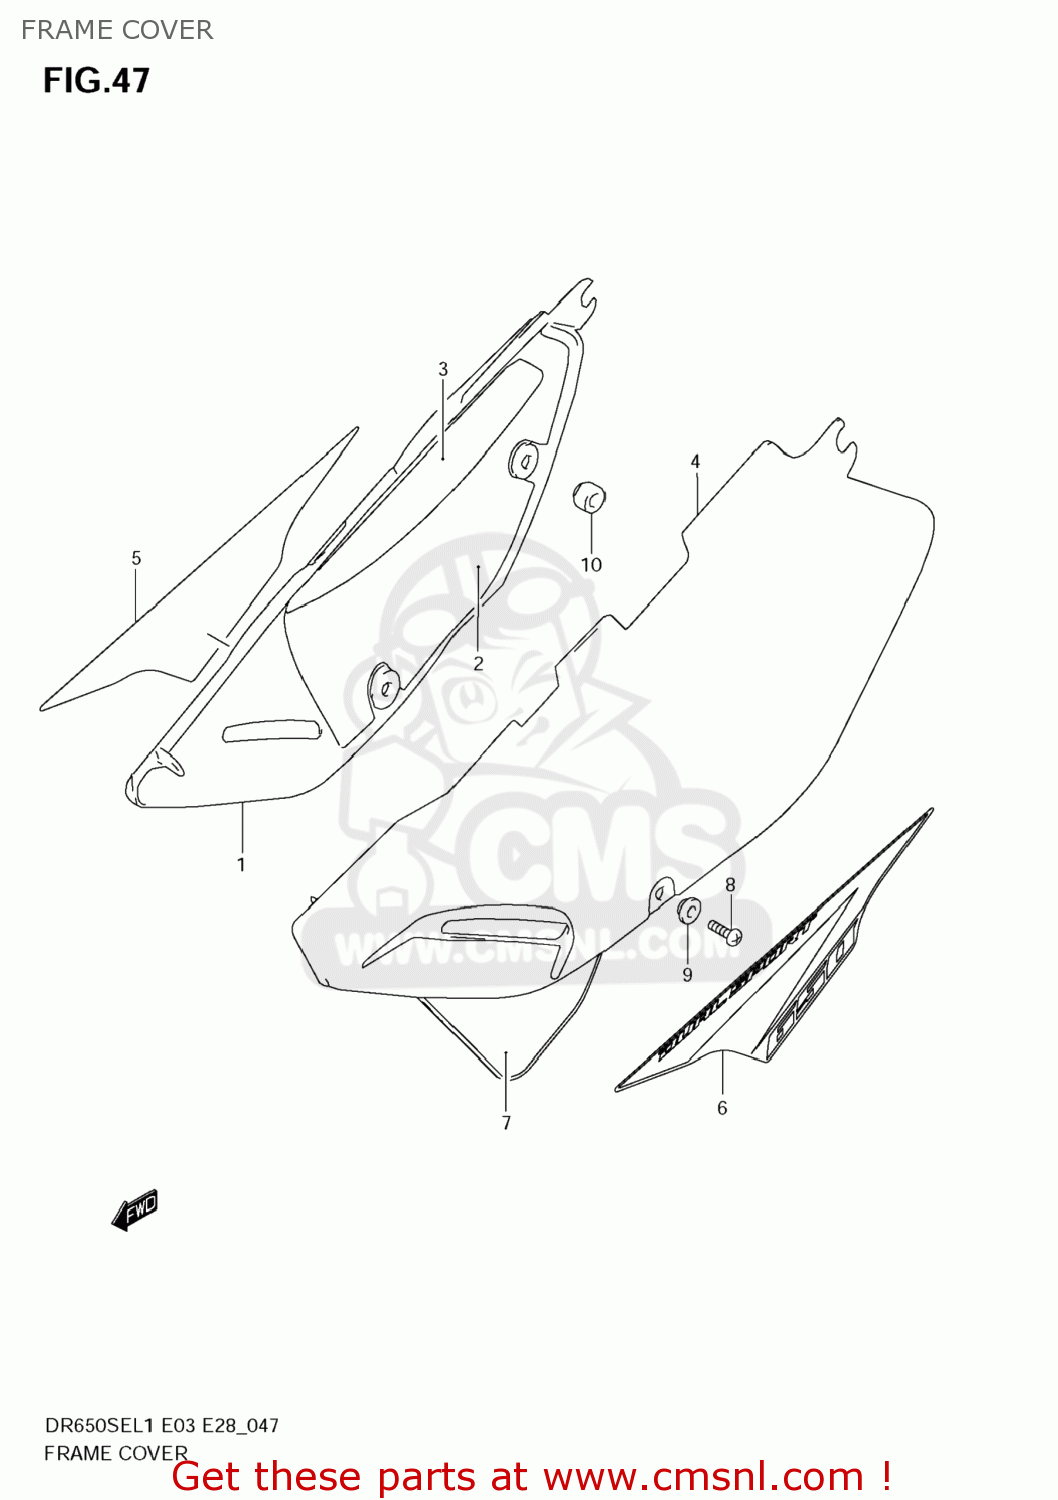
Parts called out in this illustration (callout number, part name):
1	COVER,FRAME,R(WHITE)
2	SHIELD,FRAME COVER,R NO.1
3	SHIELD,FRAME COVER,R NO.2
4	COVER,FRAME,L(WHITE)
5	TAPE,FRAME COVER,R
6	TAPE,FRAME COVER,L
7	TAPE,LWR
8	SCREW
9	WASHER
10	CUSHION
